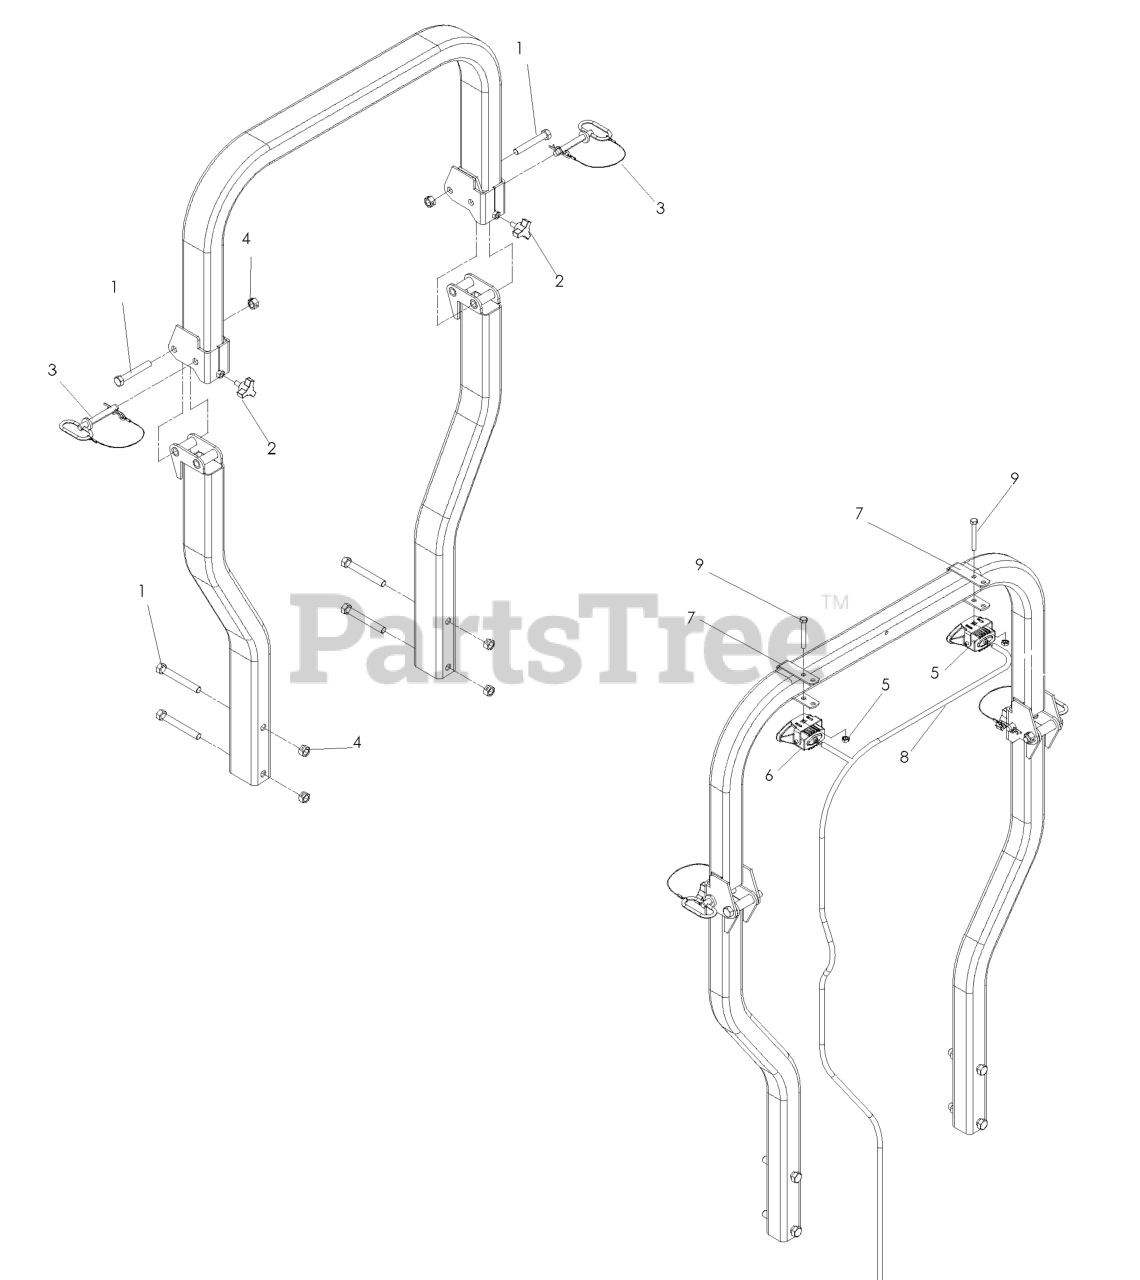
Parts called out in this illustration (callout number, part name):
1	HCS 1/2C X 3 1/4
2	KNOB W/STUD 3/8-16 X 1.5
3	PIN, 1/2" W/LANYARD
4	NUT 1/2-13 HEX CNTRLK GR 5 ZD
5	NUT 5/16-18 HEX JAM ZD
6	LIGHT 35W W/BRKT
7	LIGHT MOUNTING BRACKET
8	LIGHT HARNESS
9	BOLT 5/16C X 2 1/2
